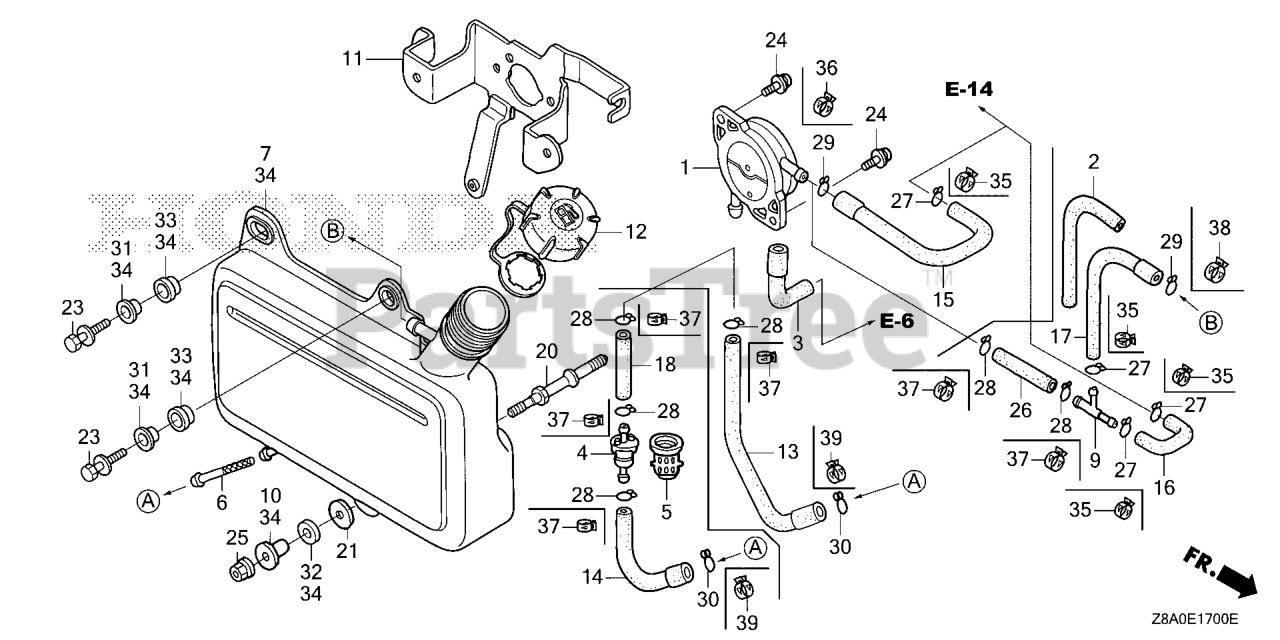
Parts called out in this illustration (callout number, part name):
1	PUMP ASSY., FUEL (MSDS)
3	TUBE, DIAPHRAGM
6	FILTER, FUEL
7	TANK, FUEL
10	COLLAR, FUEL TANK SETTING
11	STAY A, FUEL TANK
12	CAP ASSY., FUEL TANK
13	TUBE, FUEL TANK (FKM)
15	TUBE, FUEL (FKM)
20	BOLT, FUEL TANK STUD (H=30MM)
21	WASHER (6MM)
23	BOLT-WASHER (6X25)
24	SCREW-WASHER (5X14)
25	NUT, FLANGE (6MM)
31	COLLAR, TANK SET
32	RUBBER A, TANK MOUNTING
33	RUBBER B, TANK MOUNTING
35	CLIP, TUBE (D8)
36	CLIP, TUBE (D8.5)
37	CLAMP, TUBE (D10)
39	CLAMP, TUBE (D12)
